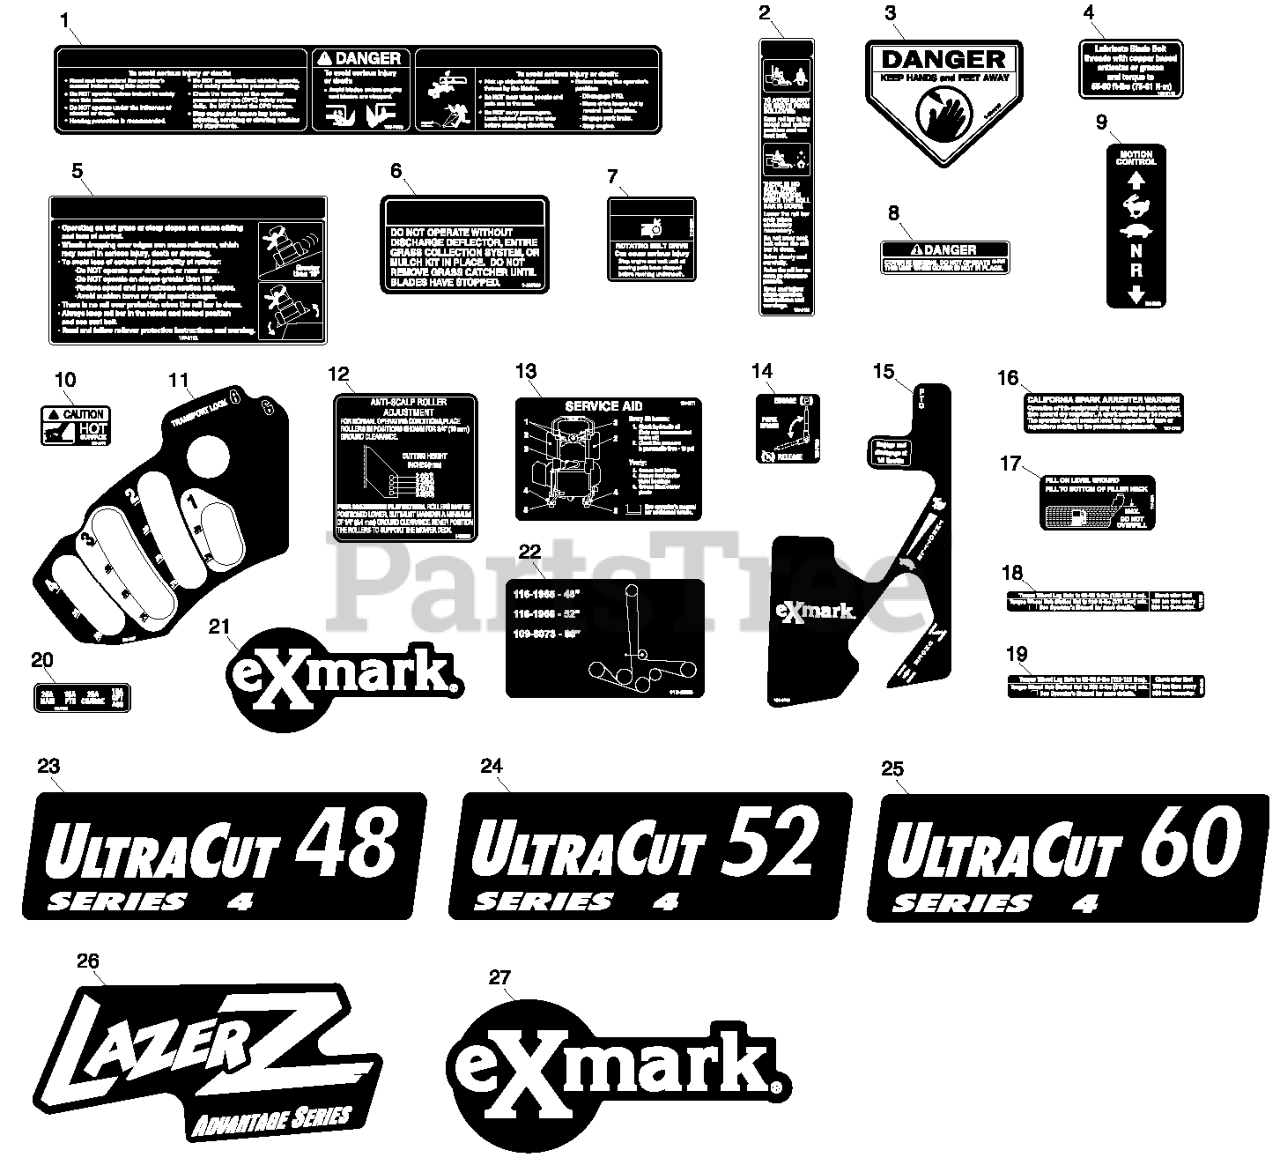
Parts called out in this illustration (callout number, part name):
1	DECAL-CONSOLE
2	DECAL-WARNING, FOLDING RO
3	DECAL-DANGER
4	DECAL,BOLT TORQUE
5	DECAL-WARNING
6	DECAL-WARNING, DISCHARGE
7	DECAL-BELT DRIVE
8	DECAL-COVER, MISSING
9	DECAL-MOTION CONTROL
10	DECAL-CAUTION
11	DECAL-HOC
12	DECAL,ANTISCALP
13	DECAL-SERVICE AID
15	DECAL-CONTROL PANEL
16	DECAL-ARRESTER, SPARK
17	DECAL-FUEL FILL
18	DECAL-HUB, WHEEL
20	DECAL-FUSE
22	DECAL-BELT ROUTING
23	DECAL,ULTRACUT 48 SERIES
24	DECAL,ULTRACUT 52 SERIES
25	DECAL,ULTRACUT 60 SERIES
26	DECAL,LAZER AS LOGO
27	DECAL,EXMARK LOGO
